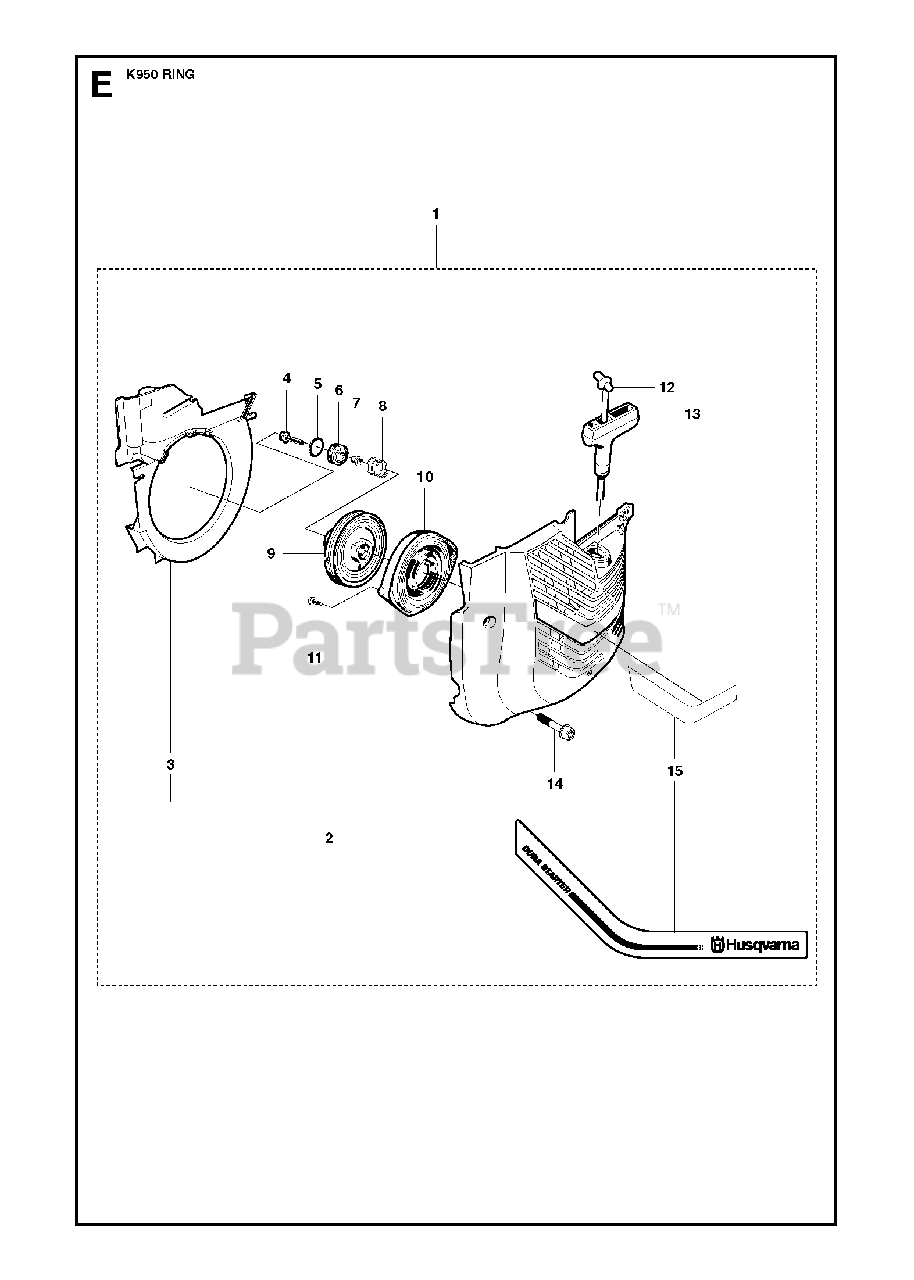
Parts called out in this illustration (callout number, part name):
4	SCREW IHSCFT
6	GROMMET
7	SPACING SLEEVE
8	COMPRESSION SPRING
9	STARTER PULLEY
10	RECOIL SPRING
11	SCREW CCRPANT
12	STARTER CORD50 m. coil
13	STARTER HANDLE
14	SCREW IHSCFMO
